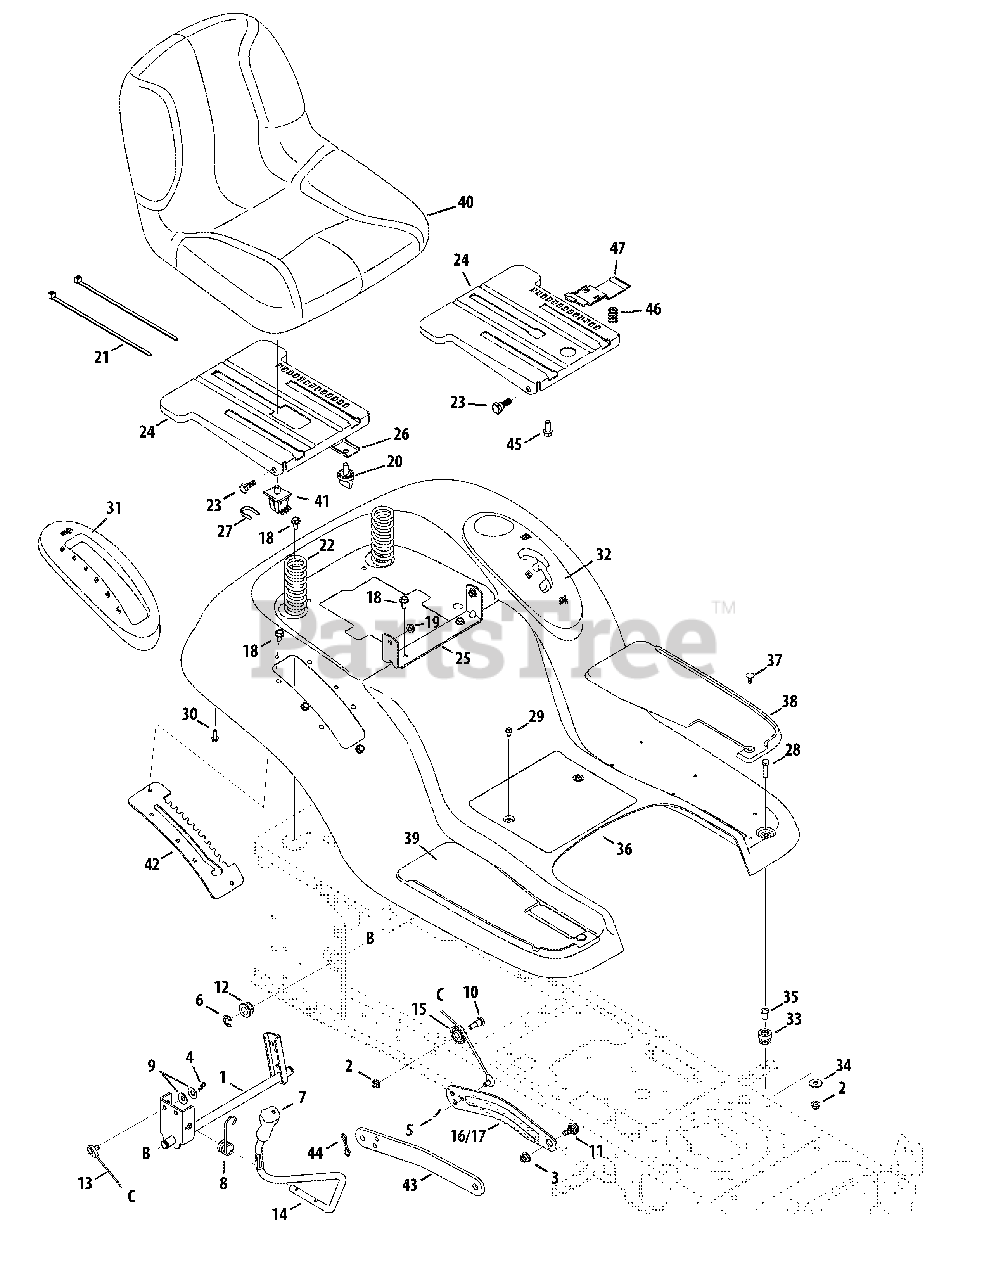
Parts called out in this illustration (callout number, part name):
1	Lift Shaft Ass’y
2	Flange Locknut 5/16-18 Gr. F, Nylon
3	Flange Lock-Nut 3/8-16 Gr. F Nylon
4	Int. Cotter Pin .072 x 1.13" Lg.
5	Bow-Tie Cotter Pin
6	E-ring .625 Shaft
8	Torsion Spring
9	Cupped Washer .375 ID x .870 OD x .063
10	Shoulder Scr. .437 Dia x .47
11	Shoulder Screw .500 x .25 (42")
12	Hex Flange Bearing .630 ID
13	Lift Cable, 16.16
15	Roller Pulley
18	Hex Wash Hd. Tapp Scr. 5/16-18 x .75
19	Hex Flange L-Nut 5/16-18
22	Compression Spring 1.71 x 3.735 x .238
23	Shoulder Screw
24	Seat Mounting Bracket
25	Seat Pivot Bracket
26	Seat Bracket, Knob adjustment
27	Switch Retaining Clip
28	Hex Bolt 5/16-18 x 1.25
29	Hex Wash S-Tapp Scr 1/4-20 x .50
30	Hex Tapp Scr 1/4 x .75" Lg.
31	Lift Lever Cover
32	Shift Lever Cover
33	Grommet .4375 ID x .75
34	Flat Washer .344 ID x 1.0
35	Flange Spacer .3125 x .4375 x .625
40	Seat, High Back
42	Lift Bracket 6 positions
42	Lift Bracket 12 positions
44	Bow-Tie Cotter Pin (46")
